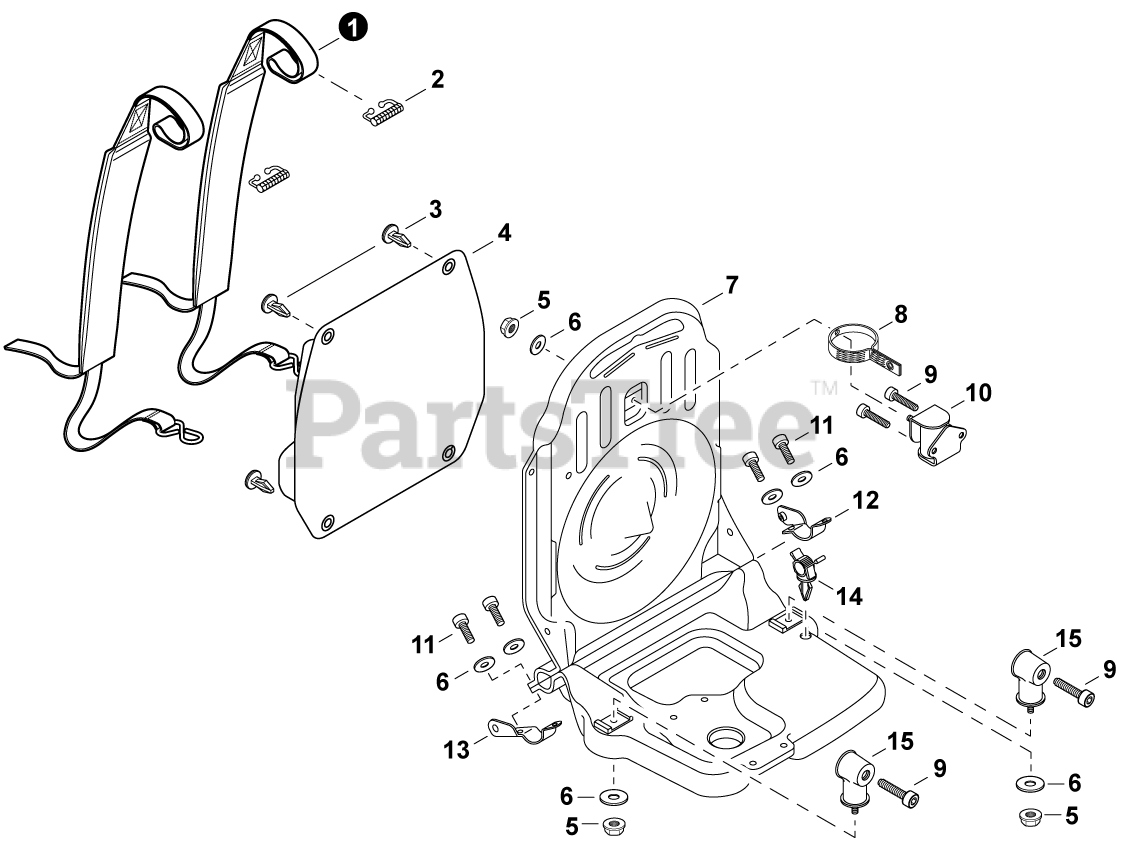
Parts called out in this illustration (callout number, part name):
1	HARNESS, BACKPACK
2	CLIP, HARNESS
4	CUSHION, BACKPACK
5	NUT, FLANGE M5
6	WASHER 5.5x16x2T
7	FRAME, BACKPACK
8	STRAP, SAFETY
9	SCREW, TAPPING 5x16
11	BOLT 5x20 HSH
12	BRACKET, HARNESS (B)
13	BRACKET, HARNESS (A)
14	CLIP, CABLE
15	CUSHION, FRAME 5
